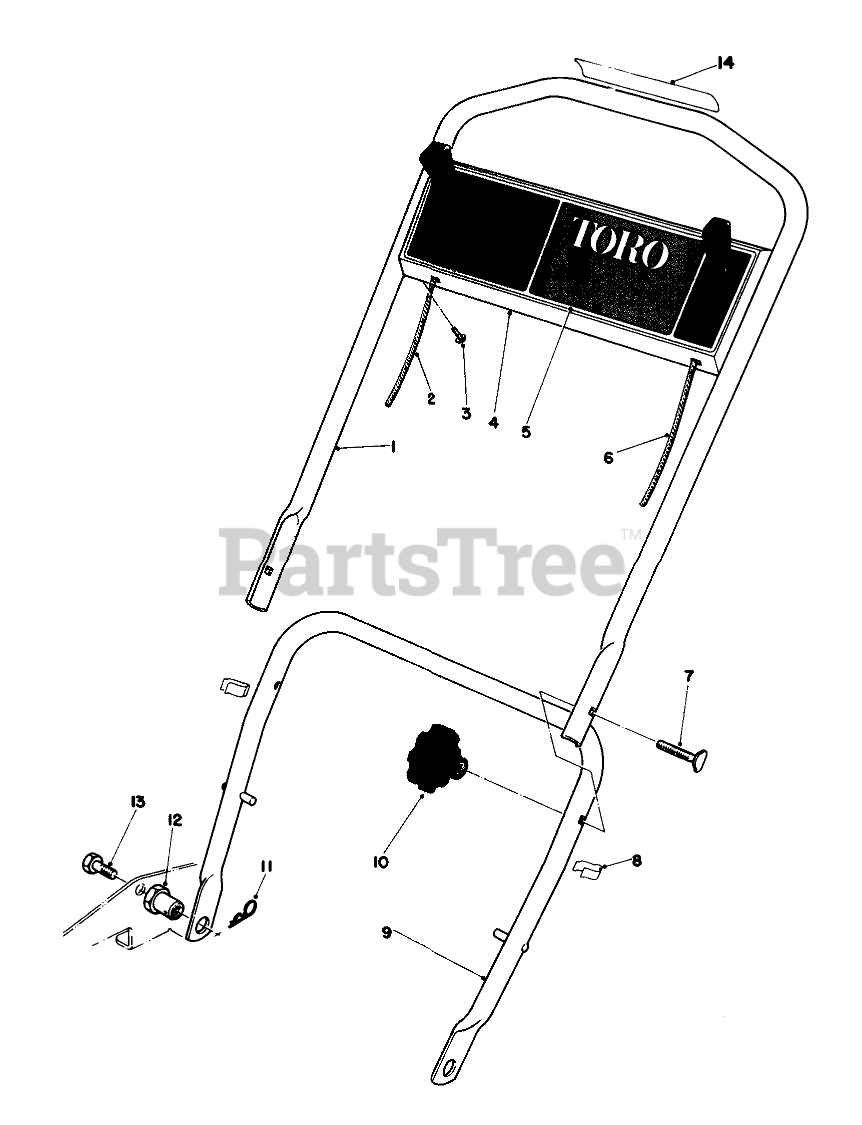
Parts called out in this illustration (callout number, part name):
1	UPPER HANDLE
2	Throttle Control
3	SCREW-HWHTF
4	Control Plate
5	Decal Control Plate
6	Control-Traction
7	SCREW-HANDLE
8	BOWDEN CLIP
9	LOWER HANDLE ASM
11	PIN-COTTER, HAIR
12	HANDLE PIVOT NUT
13	SCREW-HH
14	Decal-Instruction
